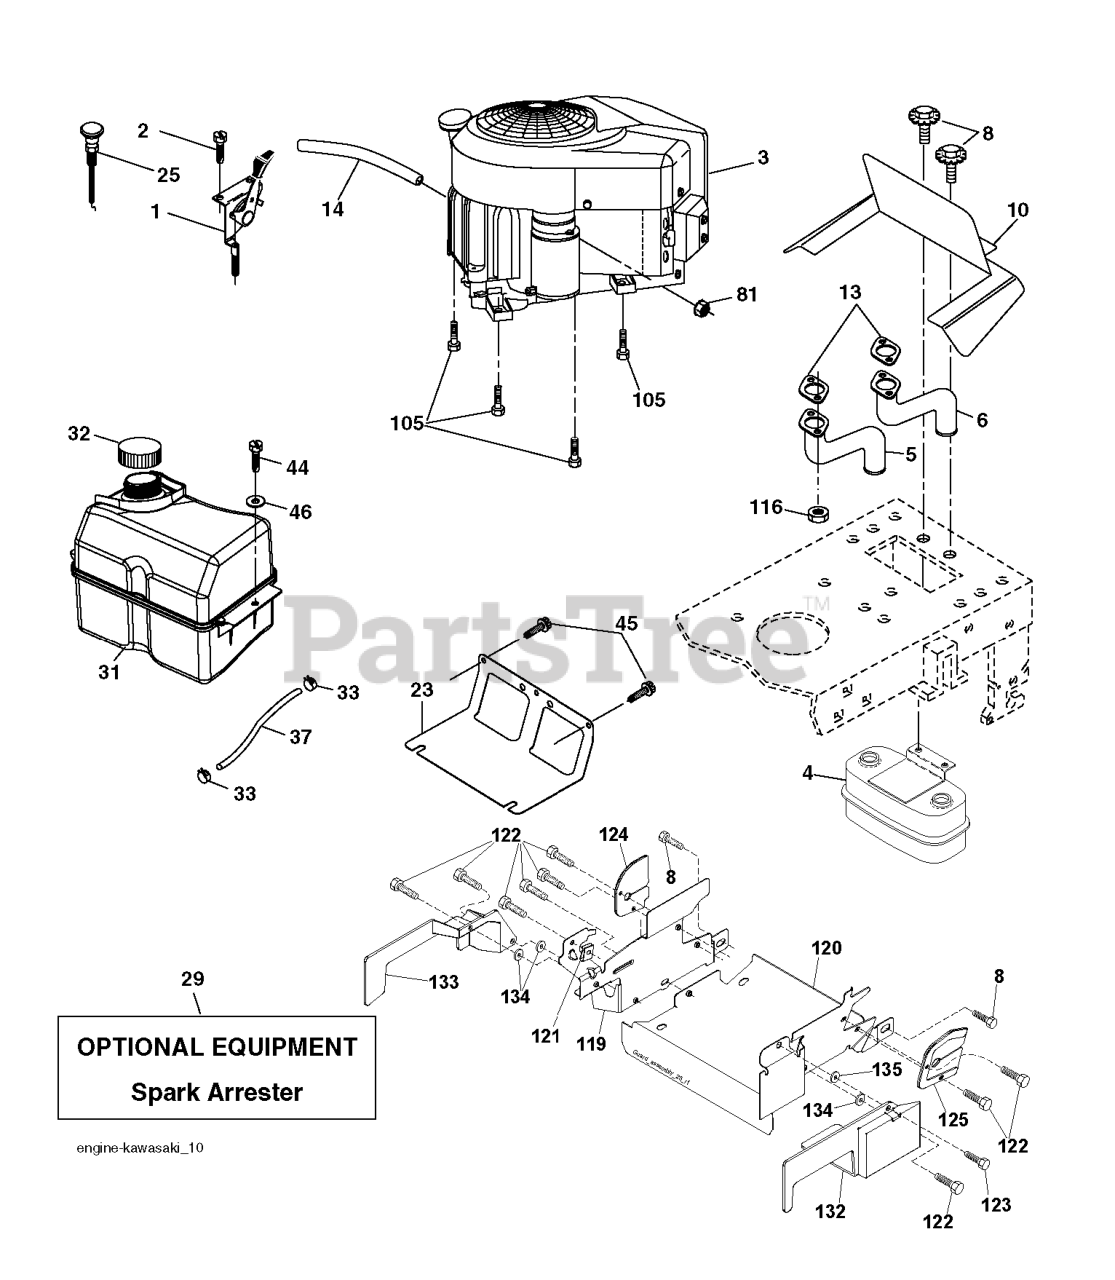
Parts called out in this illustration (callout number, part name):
1	CONTROL.THROTTLE.COBRA.BLACK
2	SCREW.#10 X 0.750.BOS
4	MUFFLER.TWIN.CYL.LOW.TONE
5	EXHAUST TUBE LH KAWI
6	EXHAUST TUBE RH KAWI
8	BOLT.5/16-18UNCX3/4 W/SEMS.BLK
10	RP SHIELD HEAT MUFFLER
14	TUBE, DRAIN OIL ASM.
23	SHIELD.BROWNING.DBR.GUARD
25	CONTROL.CHOKE.ERGO.PUSH-IN.BLA
29	KIT.SPARK ARRESTOR 794945 B&S
31	RP TANK FUEL FRT 1.5 GAL
32	FUEL CAP
33	HOSE CLAMP
37	LINE.FUEL.20
44	SCREW HEXWSHR 1/4-20X3/4
45	SCREW, 3/8-16X3/4
81	NUT
105	SCREW 3/8-16X1
116	NUT.HEX.FLANGE.TOPLOCK
119	LENKRAD
120	GUARD 532199767
122	SCREW.1/4-20X5/8
123	SCREW, 5/16-18 X 1/2
132	SHIELD RIGHT
133	SHIELD LEFT
134	PALNUT 1/4
135	WASHER 5/16"
